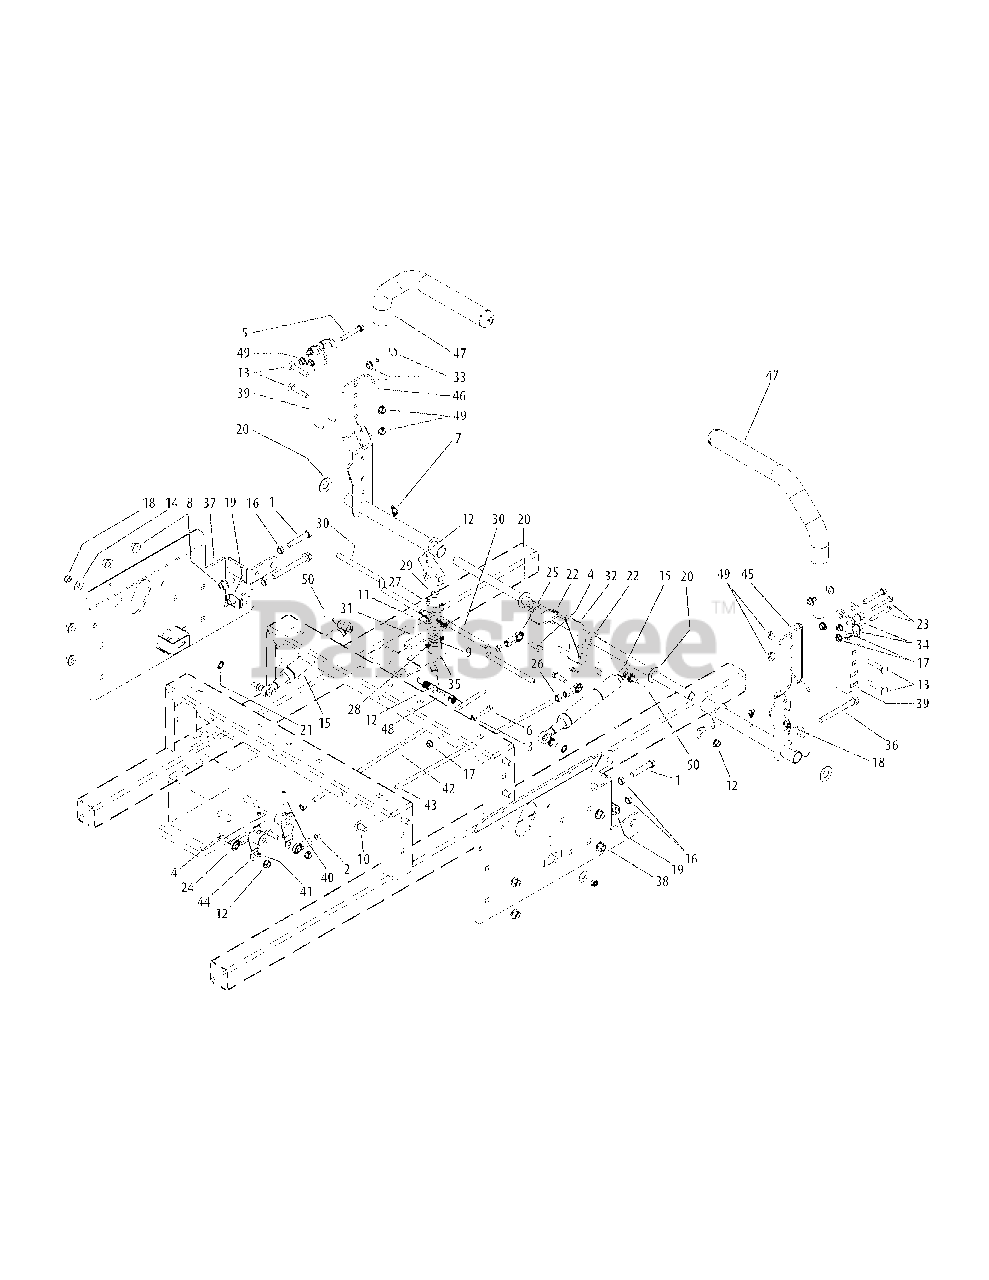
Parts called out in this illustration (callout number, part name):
1	Hex Cap Screw, 3/8-16 x 2.00
2	Hex Nut, 5/16-24
3	Hex Nut, 1/4-20
4	Hex Cap Screw, 5/16-18 x 1.0
5	Hex Cap Screw, 5/16-18 x 2.00
6	Hex Cap Screw, 1/4-20 x 1.00
8	Hex Nut, 3/8-16, Lock Flange
9	Washer, 3/8, SS
10	Carriage Bolt, 3/8-16 x .75
11	Flat Washer, 1.4 x .630 x .0515
12	Nut, Lock, HexFlange, 5/16-18
13	Carriage Bolt, 5/16-18 x 1.75
14	Belle Washer, .325 x .930 x .045
15	Cylinder Return to Neutral
16	Nut, 3/8-16, Jam
17	Hex Flange Lock Nut, 1/4-20
18	Nut, Hex, Center Lock, M8
19	U-Nut, 3/8-16, .75
20	Flat Washer, 5/8 Nylon
21	External Washer, 3/8
22	Shaft Collar
23	Hex Cap Screw, 1/4-20 x 2.00
24	Rod End, 5/16, Right Hand
25	Rod End, 5/16, Left Hand
26	Hex Nut, 5/16-24, Left Hand
27	Shoulder Bolt, 1/4 x 1/4
28	Nut w/ Star Washer, 10-24
29	Screw, Shoulder Control Rod
30	Brake/Control Rod
31	Lapbar Control Arm
32	Lapbar Control Shaft Assembly
33	Bushing, .310 x .172 x .688 x .06
34	Spacer, .251 ID x .38 OD x 1.13 LG
35	Spacer, .405 ID x 1.0 OD x .72
36	Hex Cap Screw, 3/8-16 x 3.50
37	Side Panel, Control, Left
38	Side Panel, Control, Right
39	Lapbar Pivot Bracket
40	Capscrew,, M4 x 0.7 x 25mm
41	Nut, M4 x 0.7mm, Nylock
42	Control Rod, 5/16-24, RH/LH x 19.5
43	Control Rod, 5/16-24, RH/LH x 16.5
44	Pump Mount Bracket
45	Lapbar Control Assembly, RH
46	Lapbar Control Assembly, LH
47	Lapbar Assembly includes:
47	Grip, 1.0
48	Extension Spring, .53 OD x 4.75
49	Nut, Lock, HexFlange, 5/16-18
50	Lock Washer, 5/16
